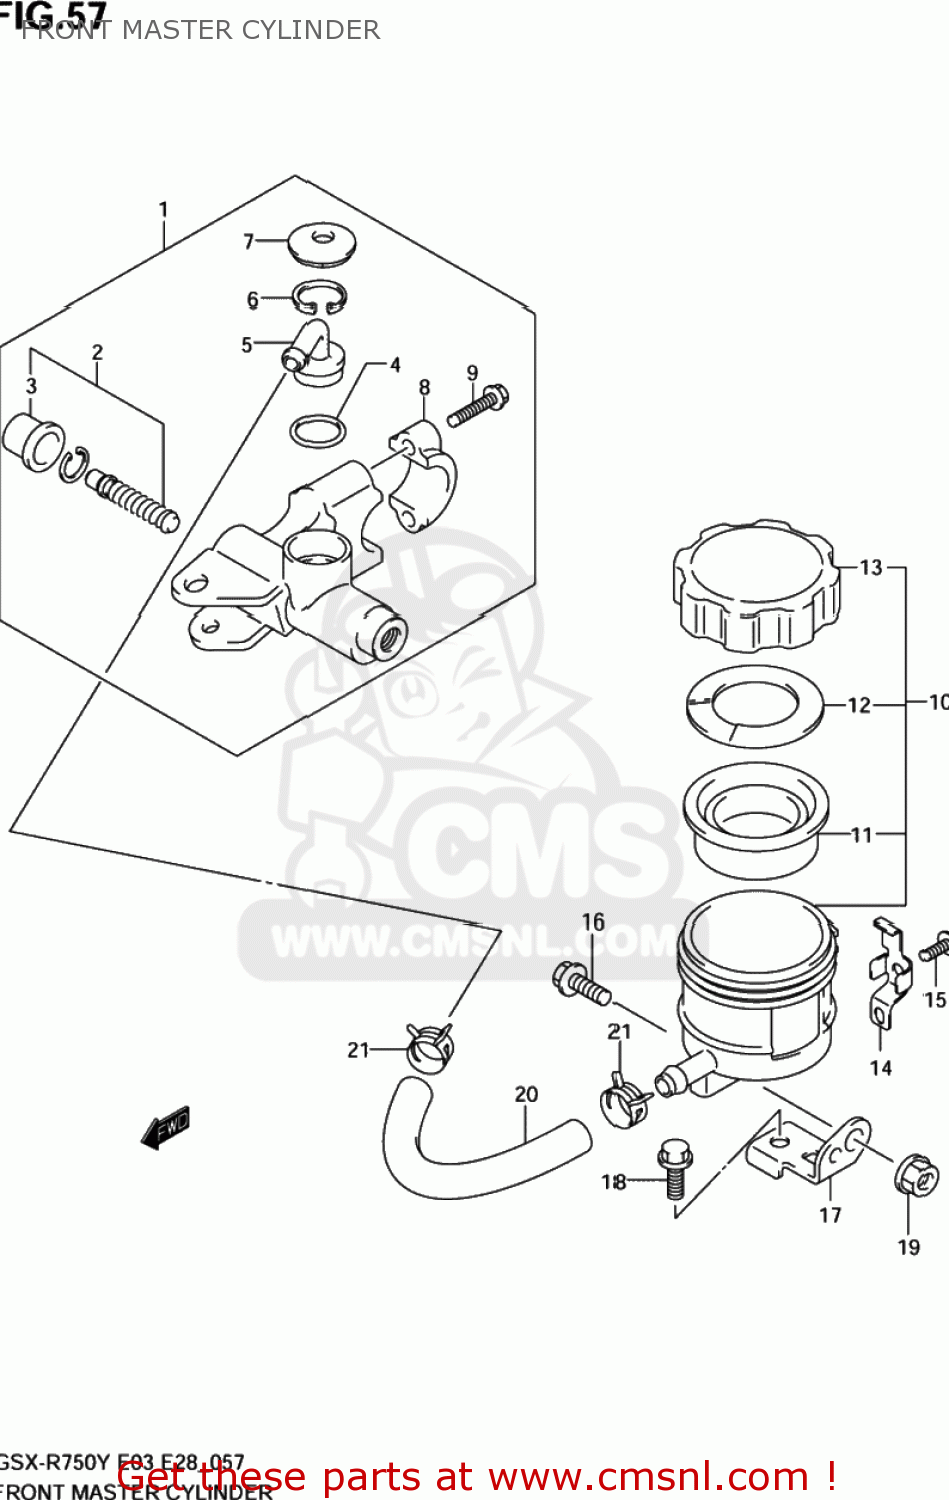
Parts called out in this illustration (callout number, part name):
1	CYLINDER ASSY,FR MASTER
2	PISTON & CUP SET
3	BOOT
4	O RING
5	CONNECTOR
6	CIRCLIP
7	COVER,DUST
8	HOLDER
9	BOLT(6X25)
10	TANK ASSY,RESERVOIR
11	DIAPHRAGM
12	PLATE,DIAPHRAGM
13	CAP
14	PLATE,RESERVOIR TANK CAP
15	SCREW
16	BOLT
17	BRACKET,RESERVOIR TANK
18	BOLT
19	NUT
20	HOSE,FR RESERVOIR TANK
21	CLAMP,RESERVOIR TANK FR
